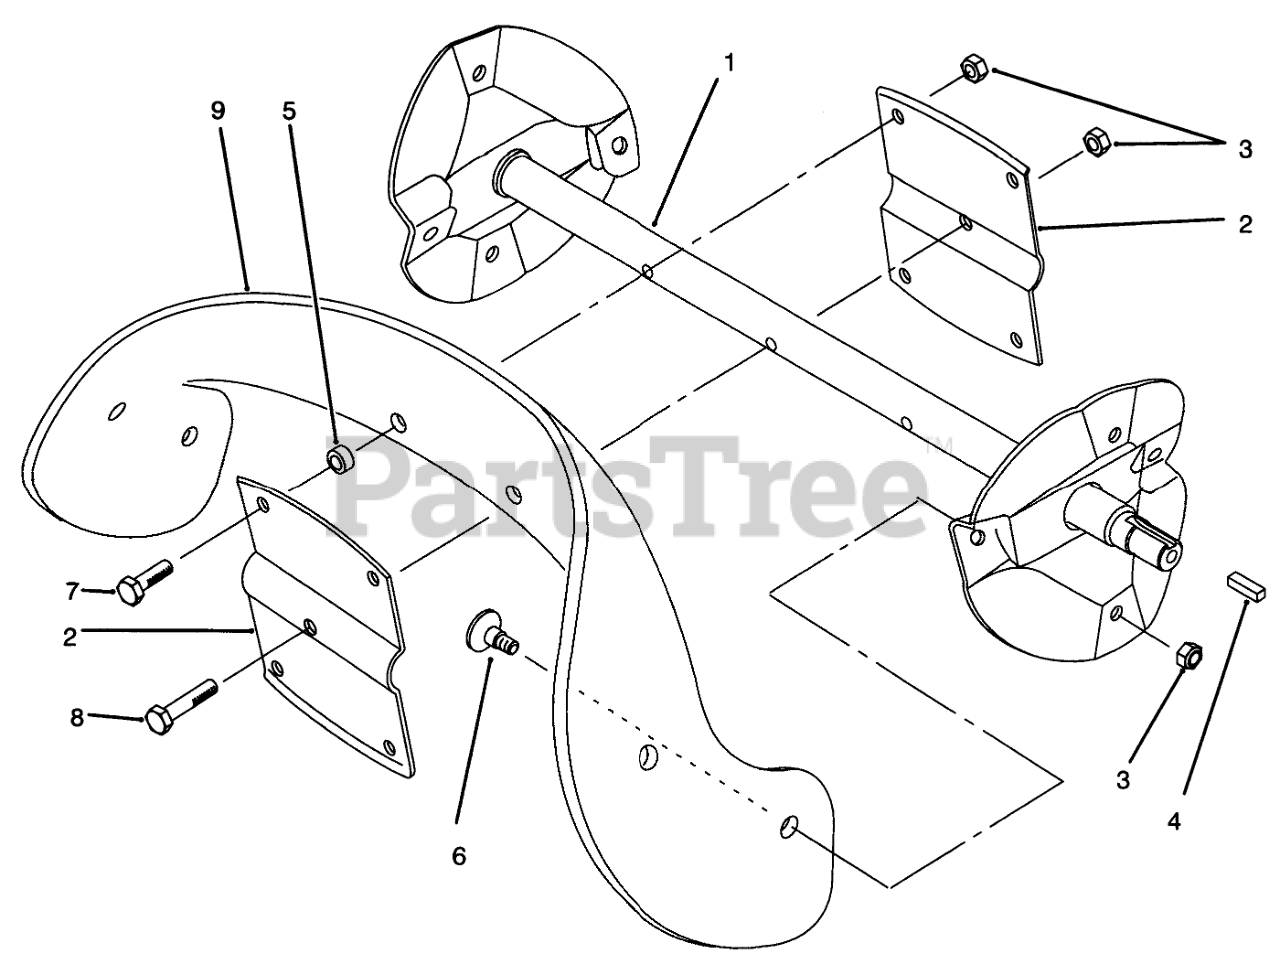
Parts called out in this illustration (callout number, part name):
1	Wa-Rotor
2	Rotor
3	NUT-LOCK, NI
4	KEY-SQUARE
5	SPACER-BLADE, ROTOR
6	SCREW
7	SCREW-HH
8	SCREW-HH
9	Blade-Rotor
